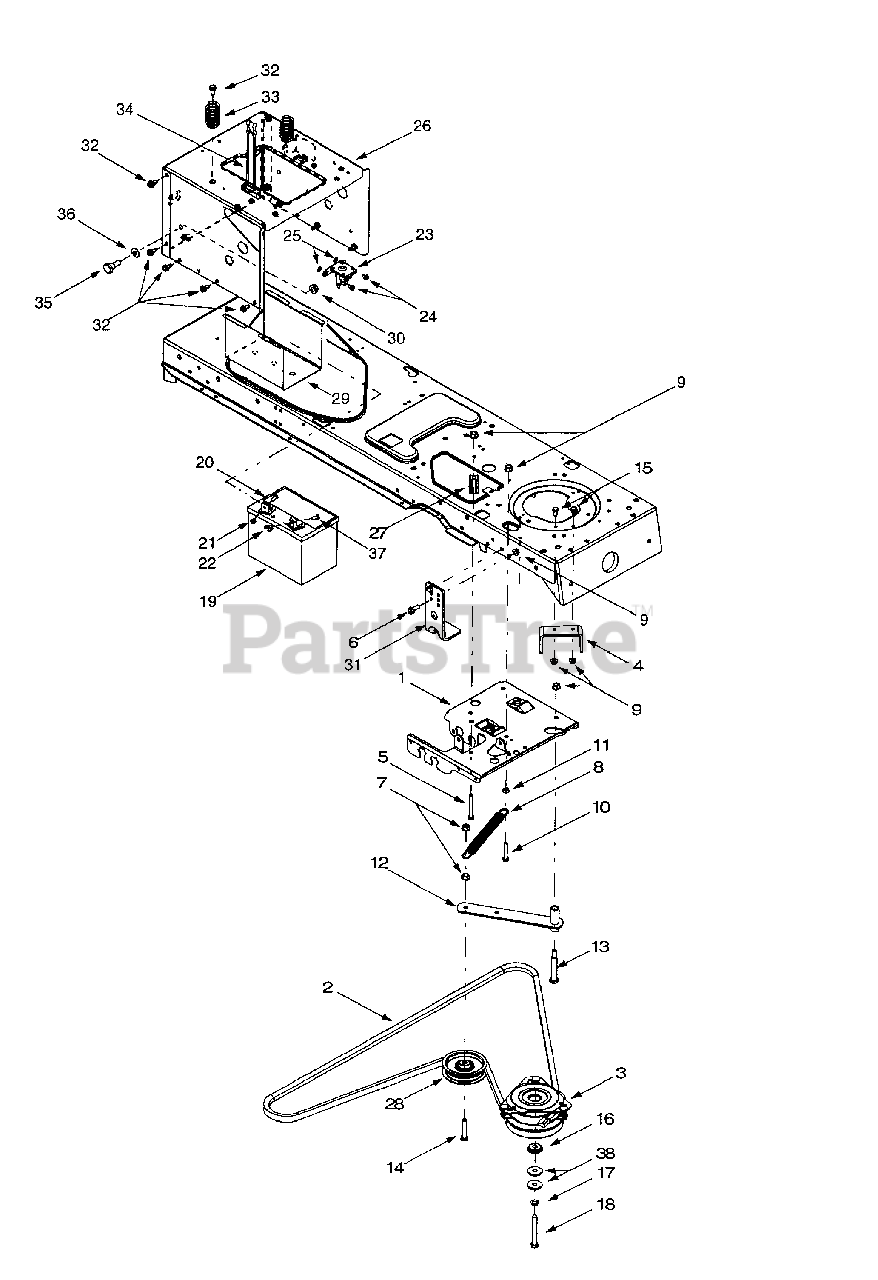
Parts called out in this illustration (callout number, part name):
2	PTO Belt
3	Electric PTO Clutch
6	Hex Head Washer Screw, 5/16-18 x .875
7	Flange Lock Nut, 3/8-16
8	Extension Spring, .62 x 5.62
9	Flange Lock Nut, 5/16-18
10	Hex Cap Screw, 5/16-18 x 1.75
11	Hex Nut, 5/16-18
12	Idler Bracket Assembly
13	Shoulder Screw, 1/2 x 2.5
14	Hex Cap Screw, 3/8-16 x 2.0
15	Hex Cap Screw, 5/16-18 x .625
16	Shoulder Spacer, 1.38 x .445 x .36
17	Lock Washer, 7/16
18	Hex Cap Screw, 7/16-20 x 3.25 (Grade 5)
19	12-volt Battery, 270 CCA
20	Hex Cap Screw, 1/4-20 x .62
21	Hex Sems Nut, 1/4-20
22	Wing Nut, 1/4-20
23	Solenoid, 12-Volt, 100 Amp
24	Self Tapping Screw, 1/4-20 x.5
25	Lock Washer, 1/4
28	Idler Pulley, 3.5
32	Self Tapping Screw, 5/16-18 x .625
33	Compression Spring, 1.28 x 3.5
34	Battery Strap
35	Shoulder Screw, .625 x .5, 7/16-20
36	Bell Washer, .45 x 1.0 x .062
37	Shoulder Screw, 1/4-20, .25 x .15
38	Flat Washer, .45 x 1.25 x .164
